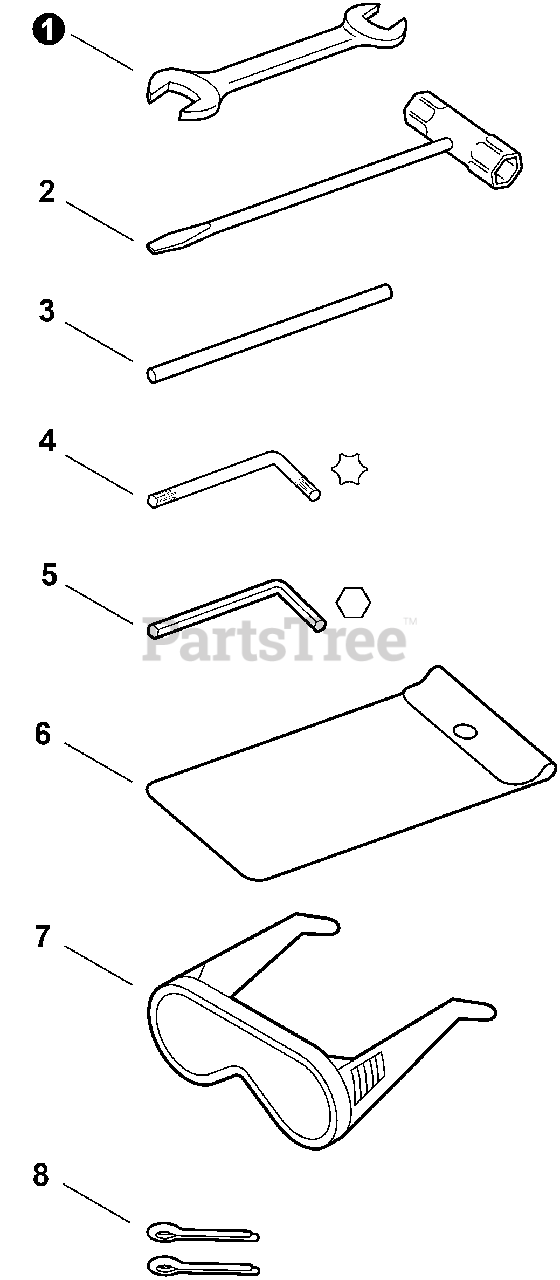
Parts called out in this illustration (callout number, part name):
1	SPANNER 8×10
2	T-WRENCH - 17×19mm
3	ROD, LOCKING
4	TOOL,L WRENCH
5	TOOL,L WRENCH
6	BAG, TOOL
8	PIN, SPLIT 2×22
